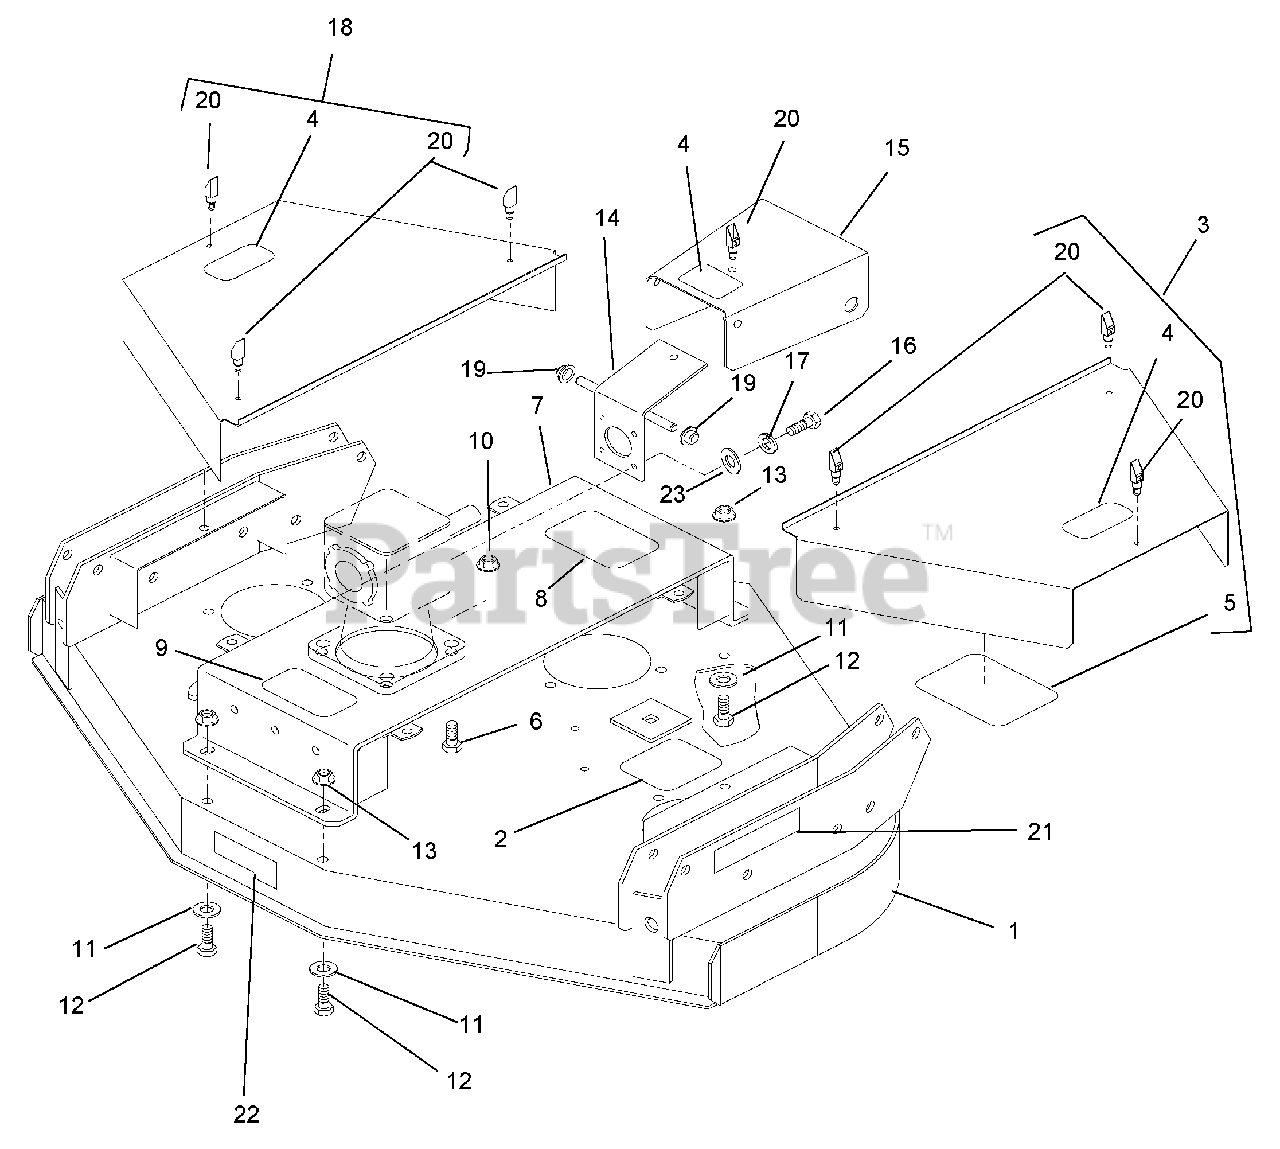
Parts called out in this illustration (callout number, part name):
1	Deck With Decals
2	Decal, Danger
3	Shield, RH Belt With Decals (Includes items 4, 5 and 20)
4	Decal, Warning
5	Decal, Belt Installation
6	Cap Screw, Hex Head .625-11 x 1.75
7	Stand, Gearbox With Decals
8	Decal, Warning
9	Decal, Danger
10	Nut, Flange Lock .625-11
11	Washer, Flat .50
12	Cap Screw, Hex Head 1/3-13 x 1-1/4
13	Nut, Flange Lock .50-13
14	Weldment, Base
15	Shield With Decal
16	Cap Screw, Hex Head M8 x 20
17	Washer, Lock .312
18	Shield, Belt LH With Decals (Includes items 4 and 20)
19	Cap, ILS
20	Latch, Swell
21	Decal, Model MP-3132
22	Decal, 9.5-inch Gravely Logo Decal
23	Washer, Flat 5/16 SAE Hard YZ
